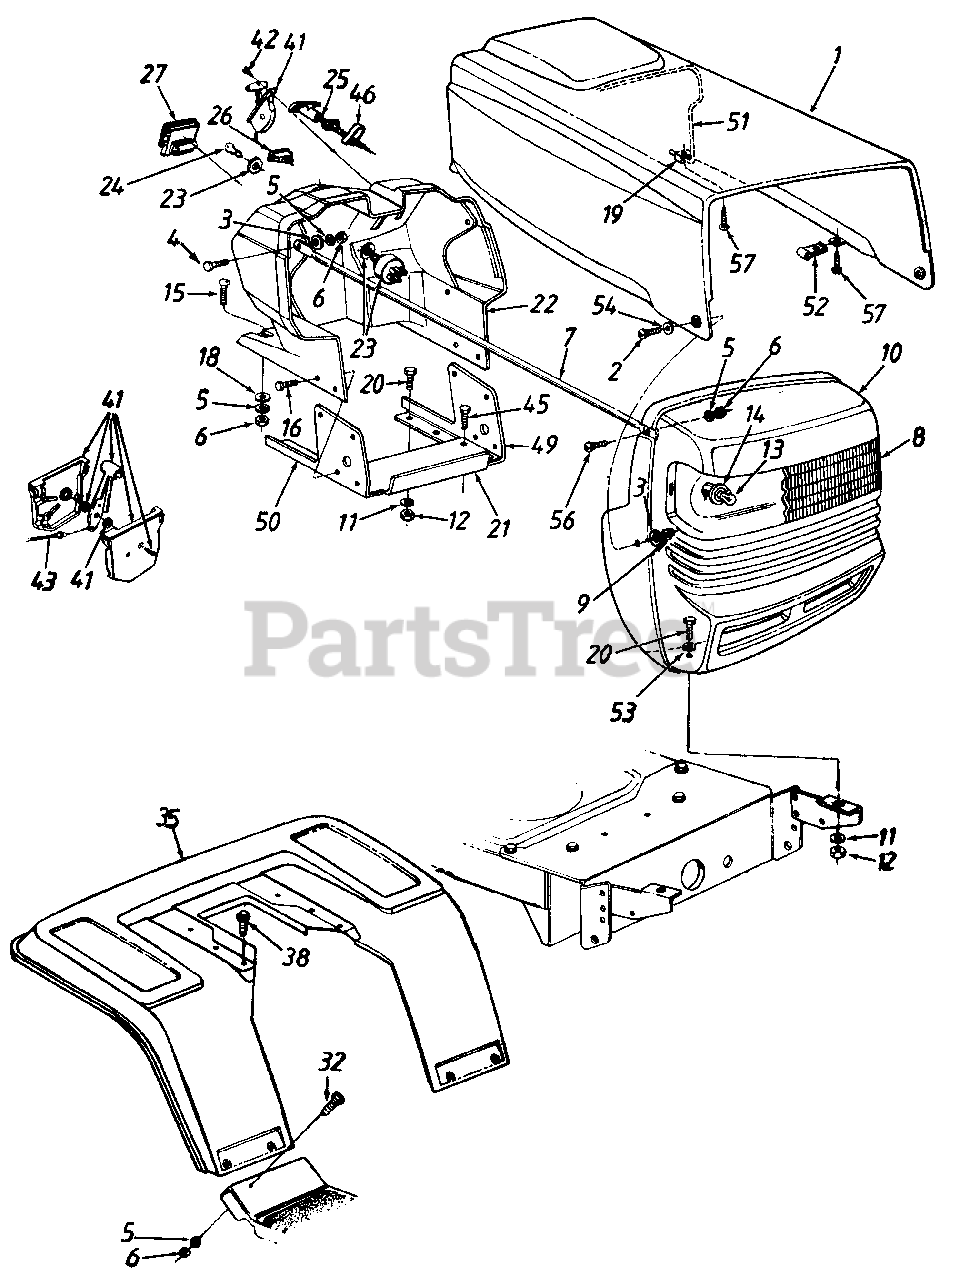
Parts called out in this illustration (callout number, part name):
3	Fl-Wash. .28" I.D. x .75" O.D.
4	Hex Bolt 1/4-20 x .88" Lg.
5	L-Wash. 1/4" I.D.
6	Hex Nut 1/4-20 Thd.
9	Flange L-Nut 1/4-28 Thd.
12	Hex Nut 5/16-18 Thd.
13	Lamp
14	Socket
15	Carriage Bolt 1/4-20 x .75" Lg.
16	Hex Wash. Hd. TT-Tap Scr. 1/4-20 x .5" Lg.
18	Bolt Retainer 1/4" I.D.
19	Speed Nut #10-24 Thd.
20	Hex Bolt 5/16-18 x .75" Lg.
23	Ignition Switch
24	Ignition Key
25	Choke Control
26	Light Switch
27	Ammeter
32	Truss Mach. Scr. 1/4-20 x .5" Lg.
41	Throttle Box Ass'y.
42	Truss Mach. AB-Tap Scr. #10 x .5" Lg.
43	Throttle Control Wire
45	Hex Wash. Hd. B-Tap Scr. 5/16-18 x .5" Lg.
46	Choke Retainer
52	Flat Fastener (Special)
53	Fl-Wash. .344" I.D. x 1" O.D.
54	Spr. Wash. .39" I.D. x .62" O.D.
56	Pan Hd. Scr. 1/4-20 x .75" Lg.
57	Truss Mach. Scr. #10-24 x .5" Lg.
